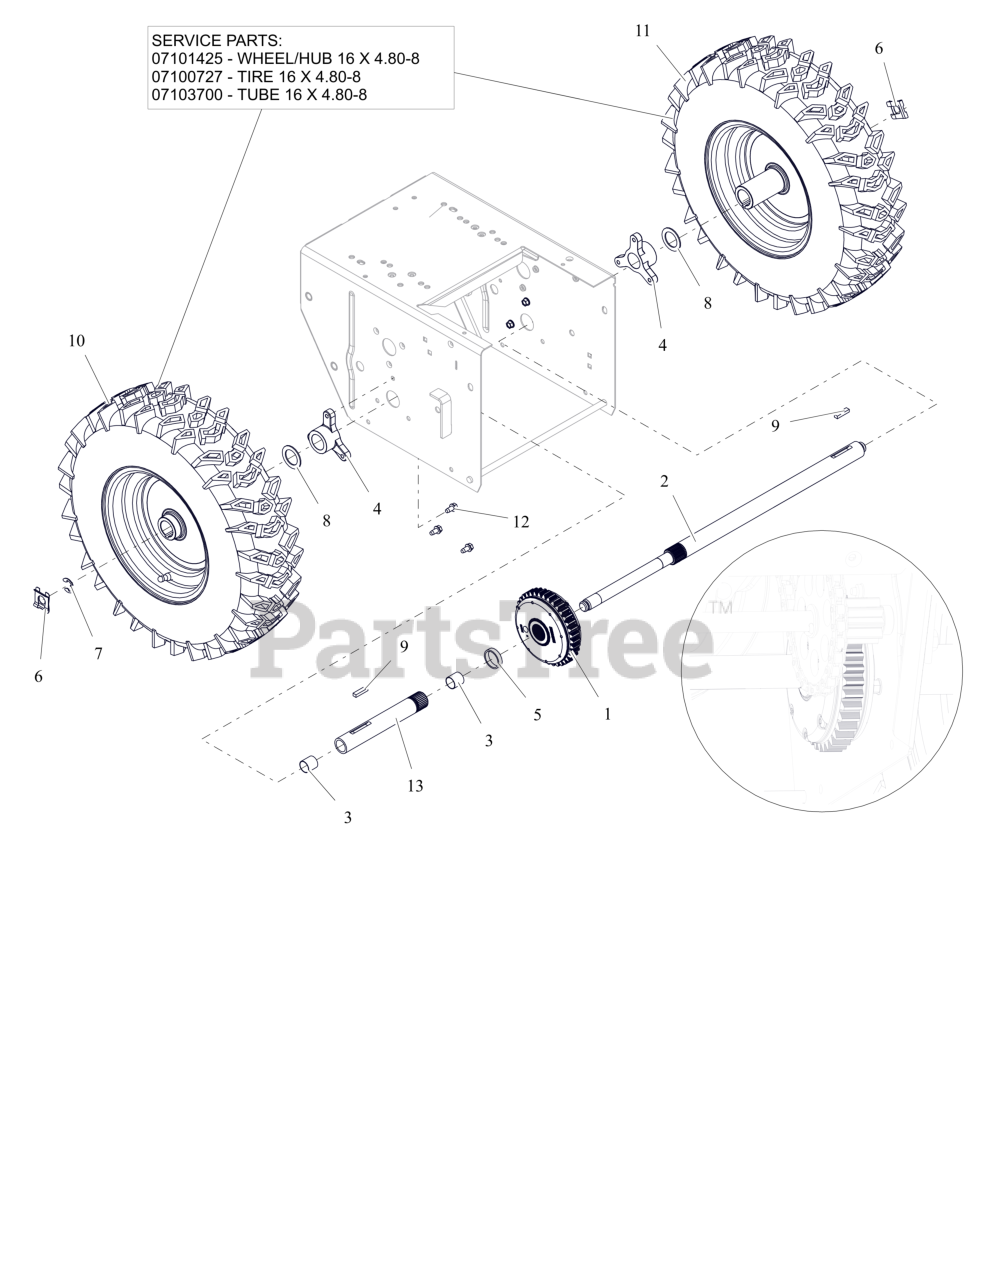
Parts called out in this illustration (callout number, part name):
1	DIFFERENTIAL, AUTOMATIC
2	AXLE,LONG-DELUXE AUTO DIFF
3	BSHG-SLV .706X.764X.75 BRZ
4	BUSHING, AXLE
5	BSHG, SLV 1.062X1.228X.268
6	CLIP, SNAP .625 DIA
7	RG-RTNG-EXT .625X.042
8	WSHR, FLT 1.010X1.505X.062 ZCC
9	KEY-RECT .25X.188X1.00
10	TIRE/WHEEL RH 16X4.8-8 DIFF T2
10	HUB, WHEEL-16X4.8-8
10	TIRE, 4.80-8 K478
10	TUBE
11	TIRE/WHEEL LH 16X4.8-8 DIFF T2
11	HUB, WHEEL-16X4.8-8
11	TIRE, 4.80-8 K478
11	TUBE
12	SCR-TAP .25-20X.50 HWH ZCC
13	AXLE, SHORT - W/BUSHINGS
